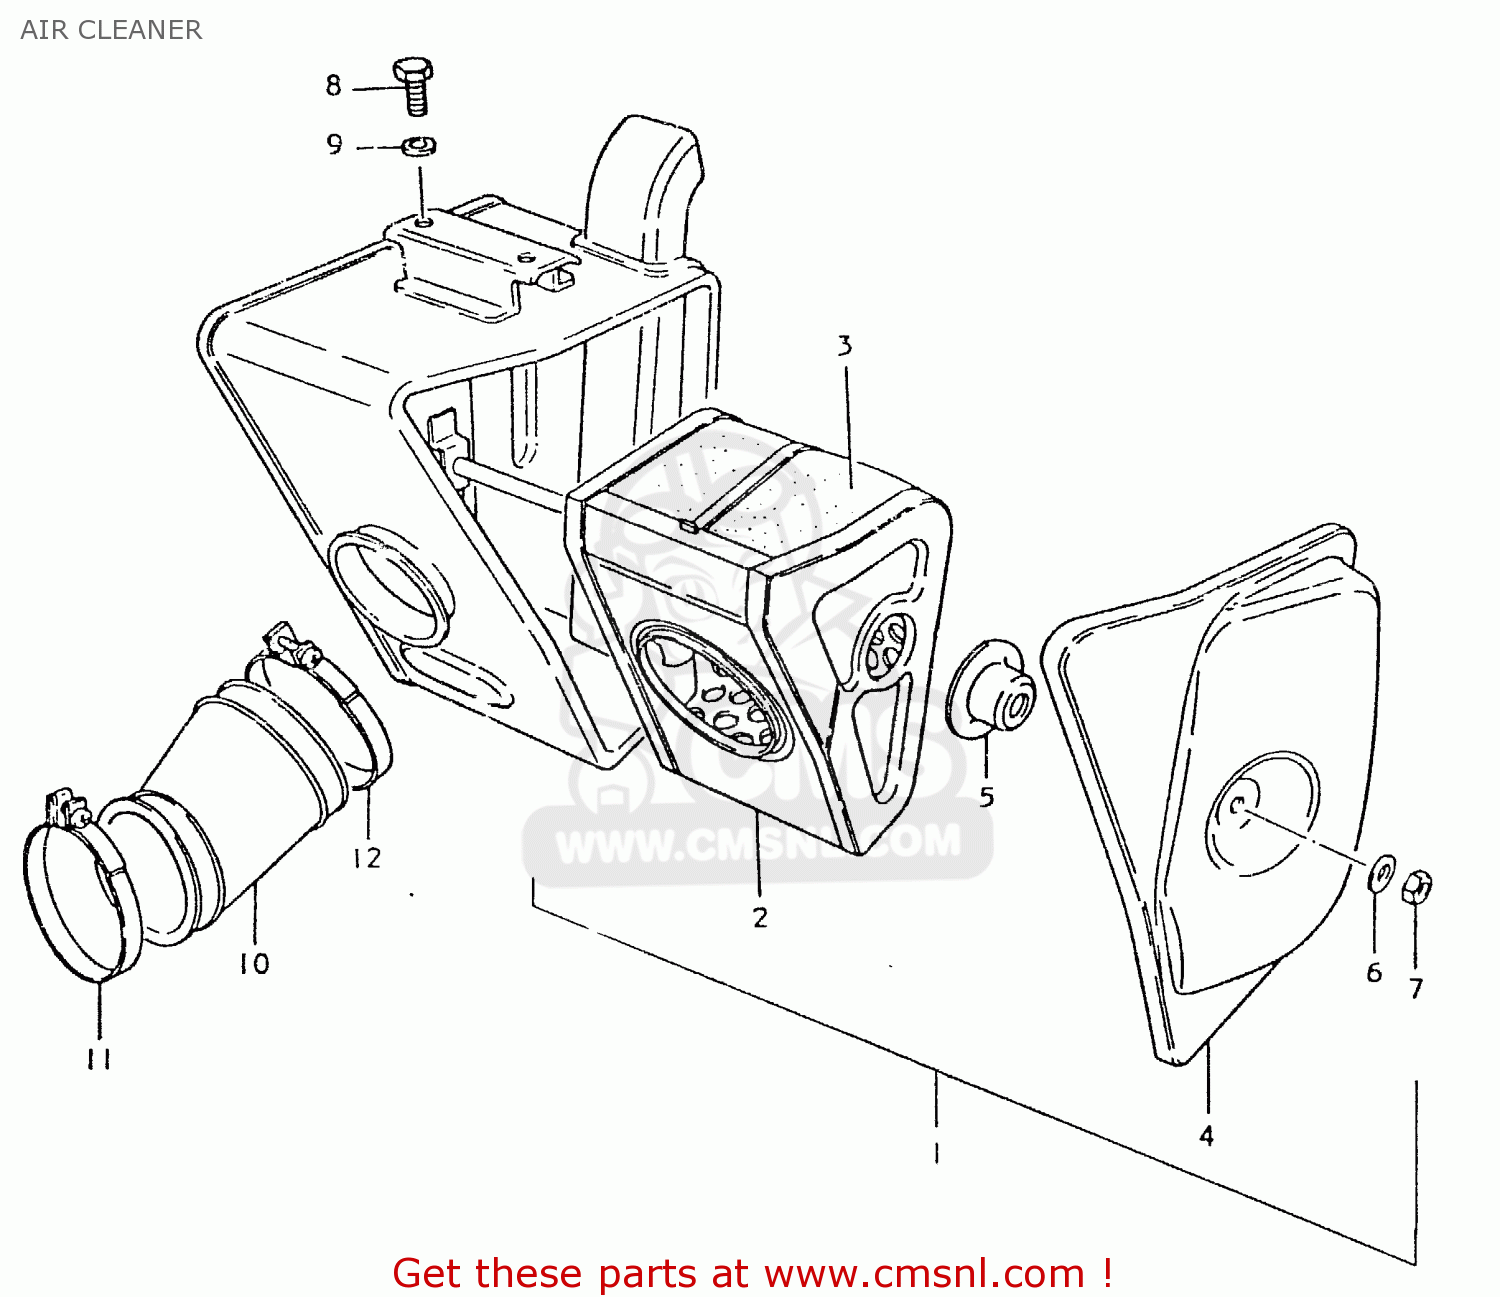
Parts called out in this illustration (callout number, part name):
1	CLEANER ASSEMBLY,AIR
2	FILTER ASSY,AIR CLEANER
3	FILTER
4	CAP
5	SPACER
6	WASHER
7	NUT
8	BOLT
9	WASHER
10	HOSE,CARBURETOR AIR INLET
11	CLAMP
12	CLAMP
